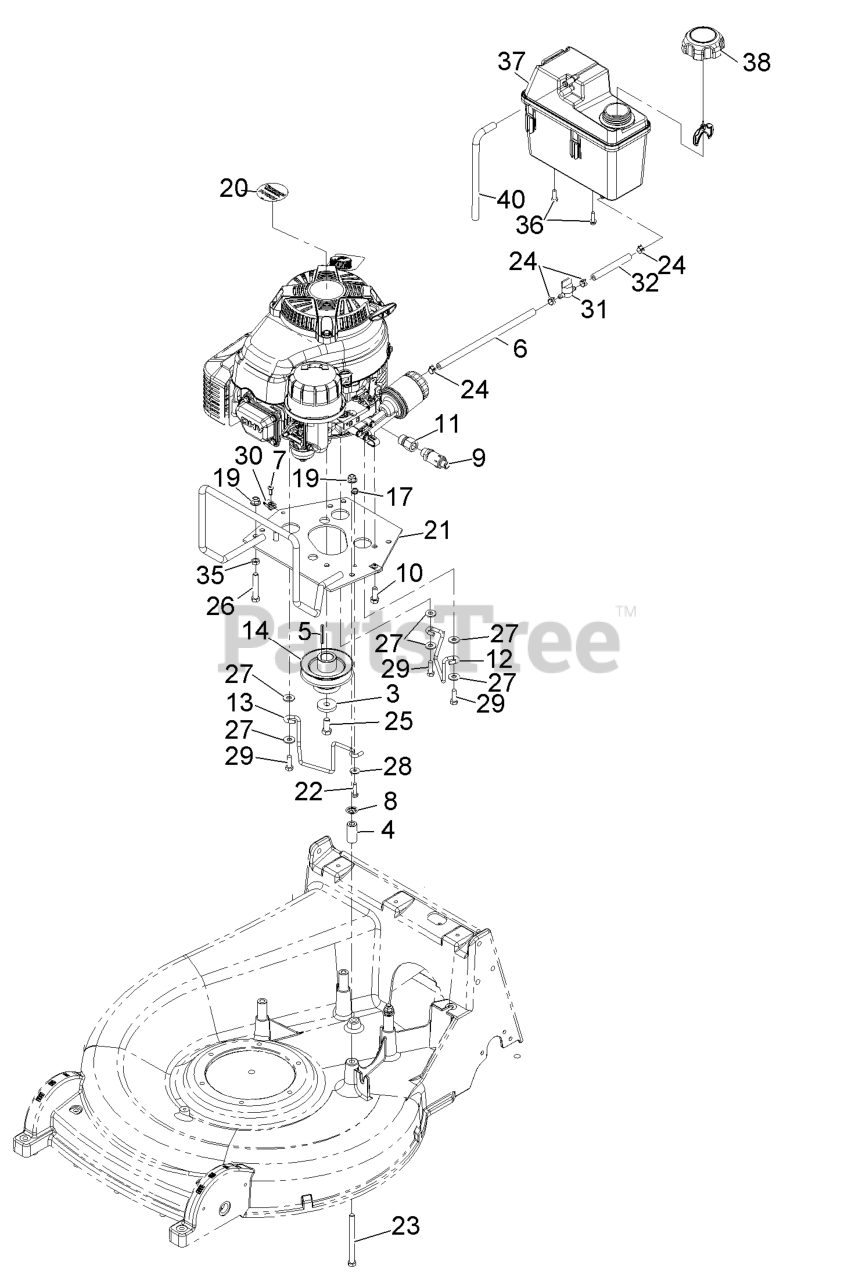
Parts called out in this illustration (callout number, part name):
3	WASHER-CLUTCH
5	KEY-SQUARE
6	HOSE-FUEL
8	RING-RETAINING
9	VALVE-DRAIN, OIL
10	SCREW-TAPTITE
11	ADAPTER
12	GUIDE-BELT, REAR
13	GUIDE-BELT, FRONT
14	SHEAVE-DRIVE
19	NUT-HF, NI
21	PLATE-ENGINE
22	SCREW-HH
23	SCREW-HH
24	CLAMP-HOSE
25	SCREW-HH
26	BOLT-CARR
27	WASHER-FLAT
28	WASHER-BELLEVILLE
29	SCREW-HH
31	VALVE-FUEL
32	HOSE-FUEL
35	NUT-JAM
36	SCREW-HWH
37	TANK-FUEL
40	HOSE-VENT, CANISTER
